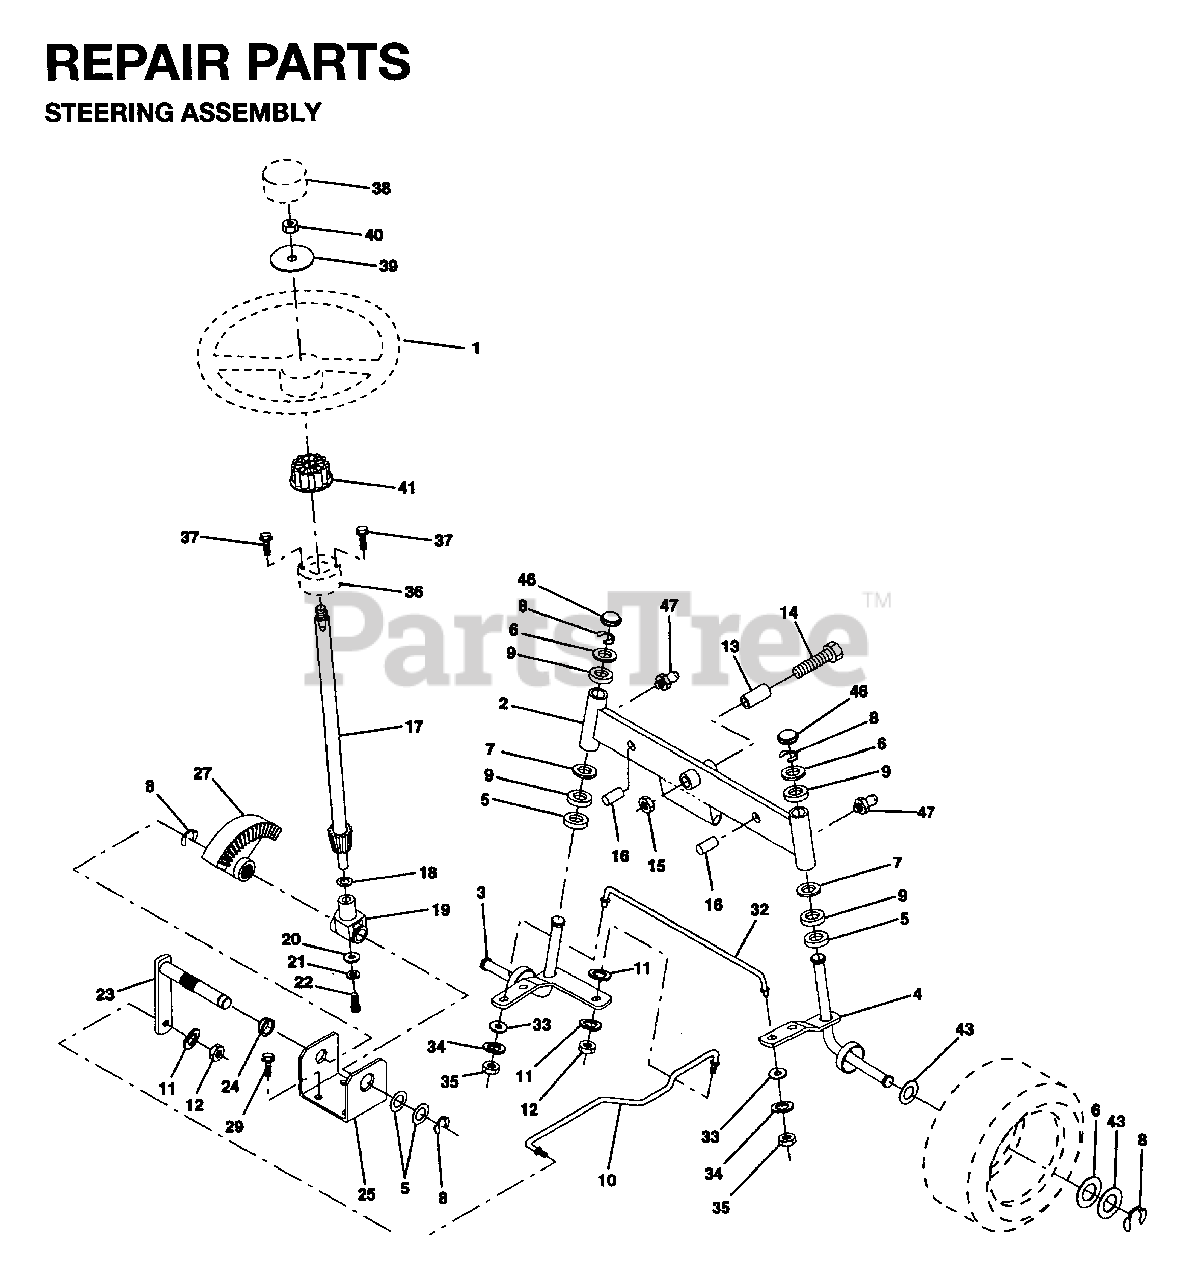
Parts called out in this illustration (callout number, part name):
2	AXLE ASSY
3	SPINDLE LH
4	SPINDLE RH
5	WASHER THRUST
8	RING CLIP
9	BEARING.STEERING.COLUMN
10	DRAG LINK
11	WASHER, LOCK 3/8
12	NUT
13	BEARING
14	BOLT.HEX.5/8-11
15	LOCKNUT
17	STEERING SHAFT
18	THRUST WASHER
19	SHAFT,SUPPORT
20	WASHER
21	LOCKWASHER
22	SCREW,SPECIAL
23	SHAFT PITMAN
24	NYLINER T
25	BRKT,STEERING
27	GEAR.SECTOR
32	TIE ROD
33	WASHER - 15X7.3X1.6
34	LOCKWASHER
36	BUSHING STRG 3/4
41	ADAPTER LT
46	CAP.SPINDLE
47	ZERK M
